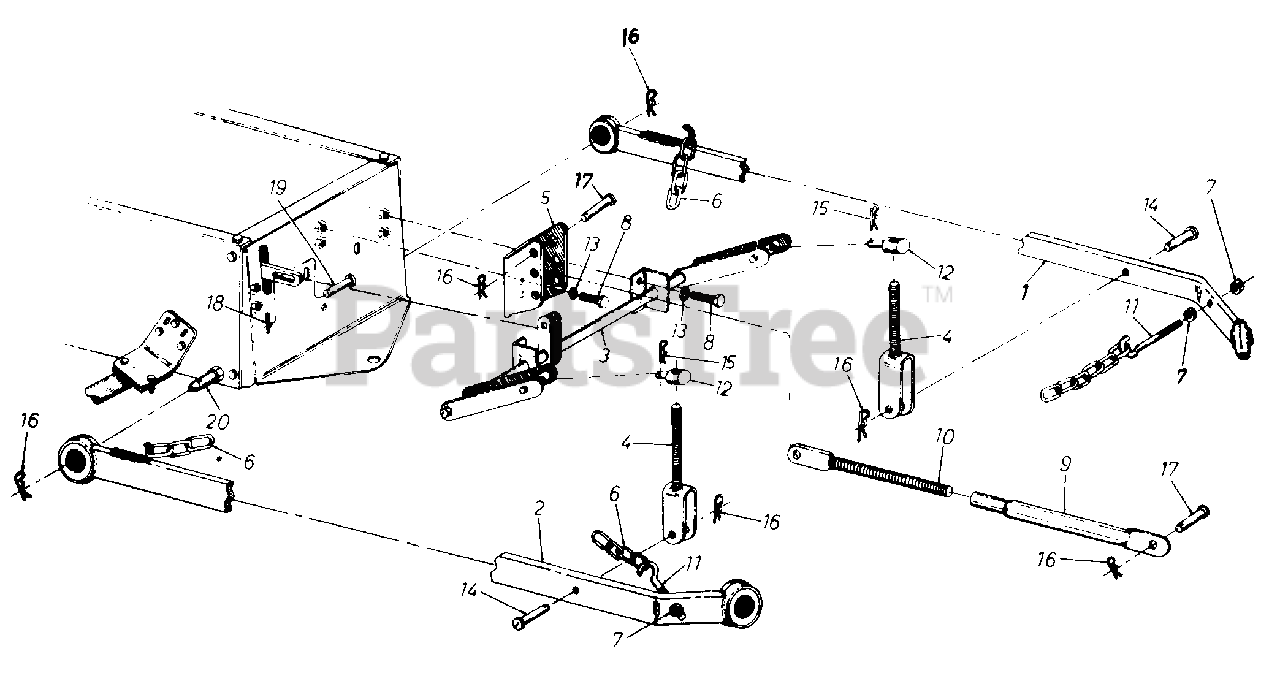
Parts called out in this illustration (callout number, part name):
1	Draft Bar Assembly-R.H.
2	Draft Bar Assembly-L.H.
6	Chain 20 links
7	Hex Cent. L.-Nut 7/16-14 Thd.
8	Hex Bolt 5-3/8-16 x Lg. Grade 5
10	Clevis Screw
11	Hitch Chain Hook
13	L.-Wash. 3/8" I.D.*
14	Clevis Pin 5/8 Dia. x 1.66 Lg.
17	Clevis Pin 5/8 Dia. x 2.4 Lg.
18	Cotter Pin 1/8 Dia. x 1-1/4 Lg.*
20	Link Clevis Pin
